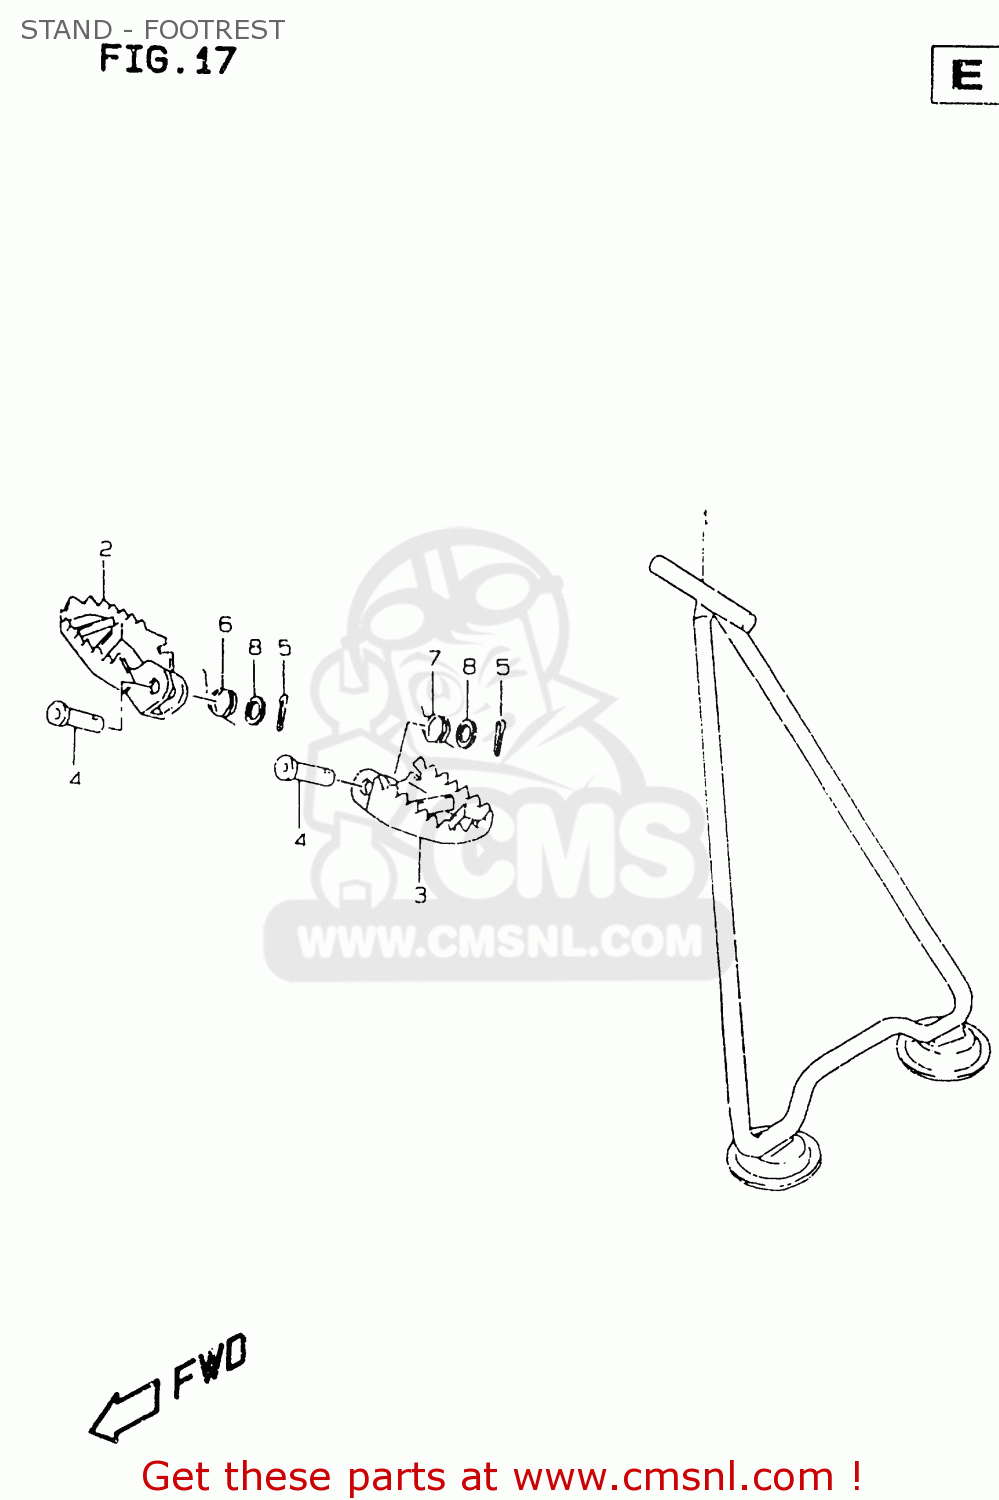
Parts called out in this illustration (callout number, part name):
1	STAND
2	FOOTREST,RIGHT
3	FOOTREST,L
4	PIN(10X41.5)
5	PIN 25X20
6	SPRING
7	SPRING
8	WASHER
